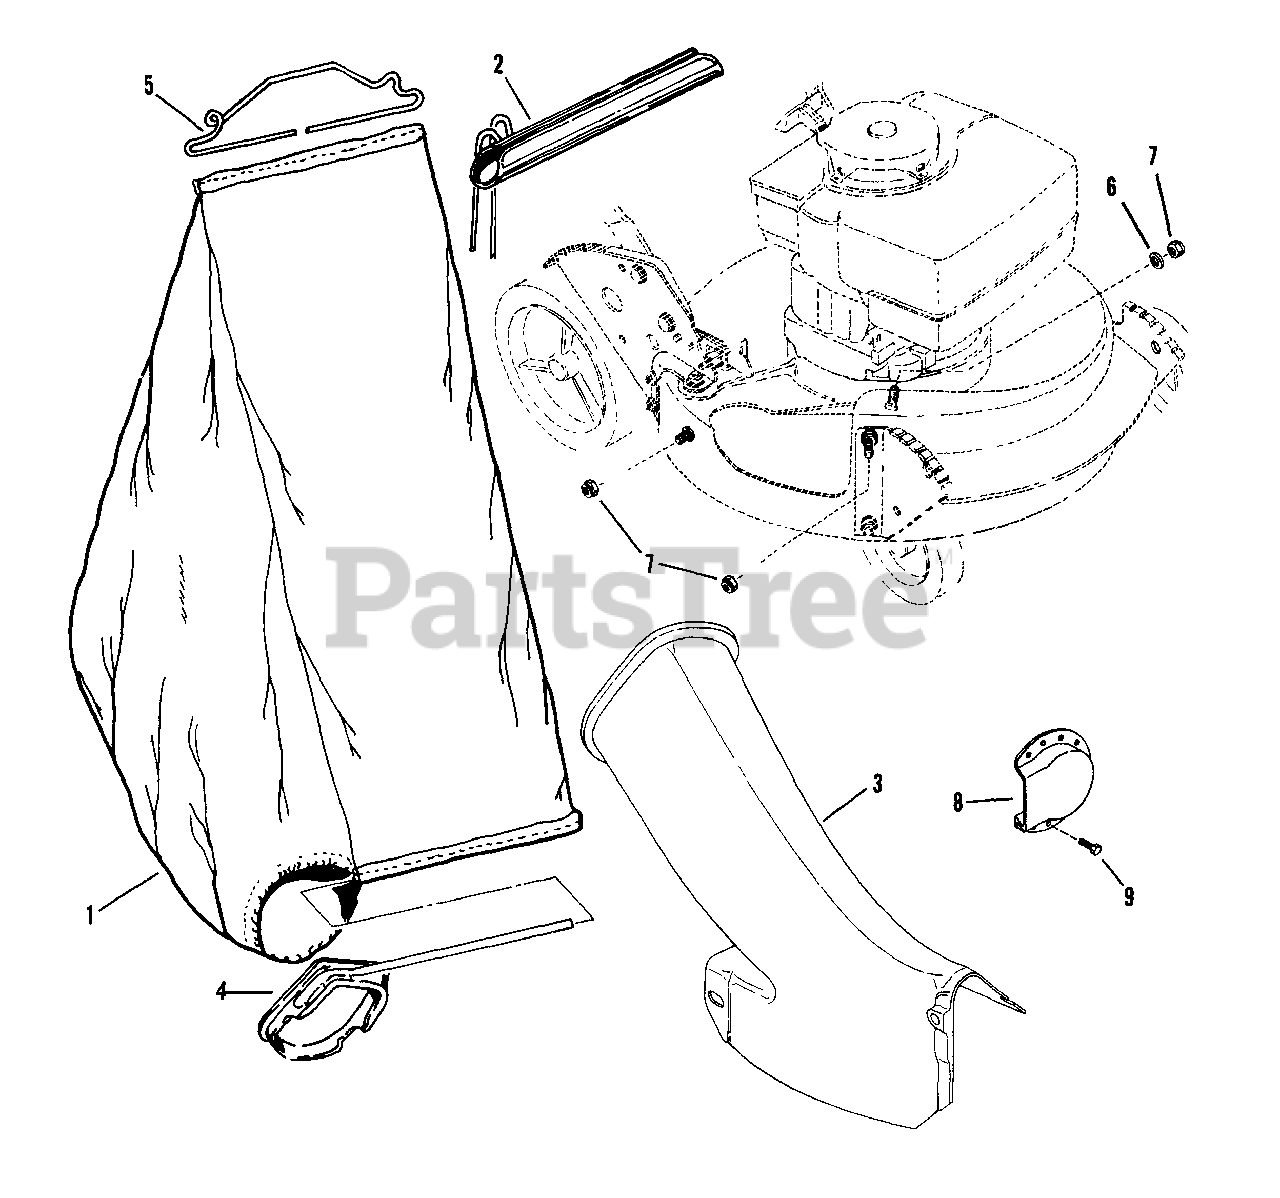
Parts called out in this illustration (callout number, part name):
1	BAG, Grass
2	ASSEMBLY, Rope & Slider
3	ADAPTER, Bag
4	CONNECTOR, Bag
5	WIRE, Bag Connector
6	WASHER, 5/16 Flat
7	NUT, 5/16-18 Hex Flange Lock
8	DEFLECTOR, Muffler
9	SCREW, #8-18 x 3/8" Hex Head Cap
